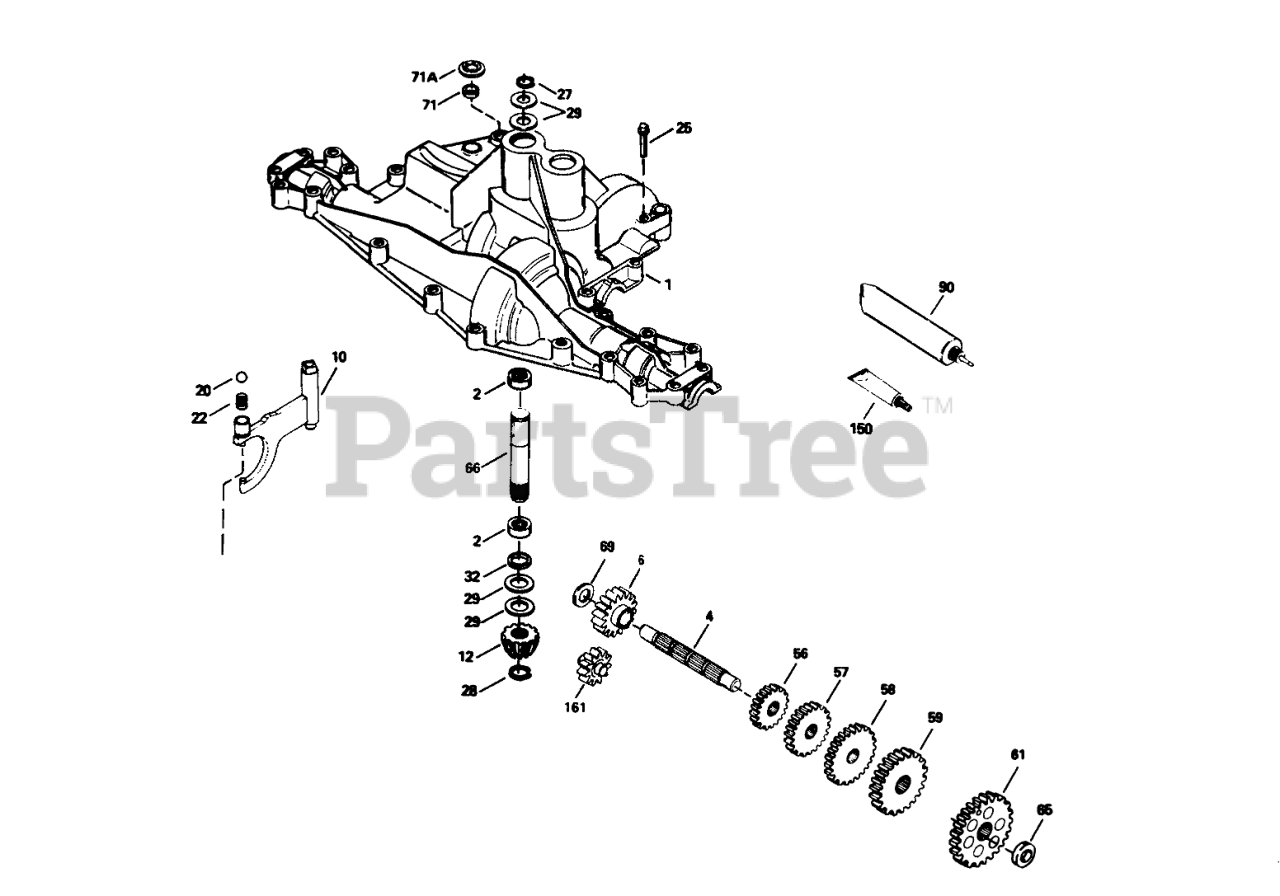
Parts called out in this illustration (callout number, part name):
1	Transaxle Cover
4	Countershaft
6	Spur Gear (16 Teeth)
10	Shift Rod & Fork
12	Bevel Pinion (14 Teeth)
20	Ball (3/8" dia.)
22	Spring
25	Ring Set (.020 O S)
27	Ring-Snap
28	Ring-Retainer
29	Washer
32	O Ring
56	Gear-Spur, 15 Teeth
57	Gear-Spur 23 Teeth
58	Spur Gear (21 Teeth)
59	Gear-Spur (30 teeth)
61	Spur Gear (34Teeth)
65	Washer
66	Input Shaft (3.522" Ig.)
69	Thrust Washer
71	Cut Seal-Square
71A	Pushnut
90	Grease 32 Oz
150	Gasket Eliminator
161	Reverse Idler Assembly
